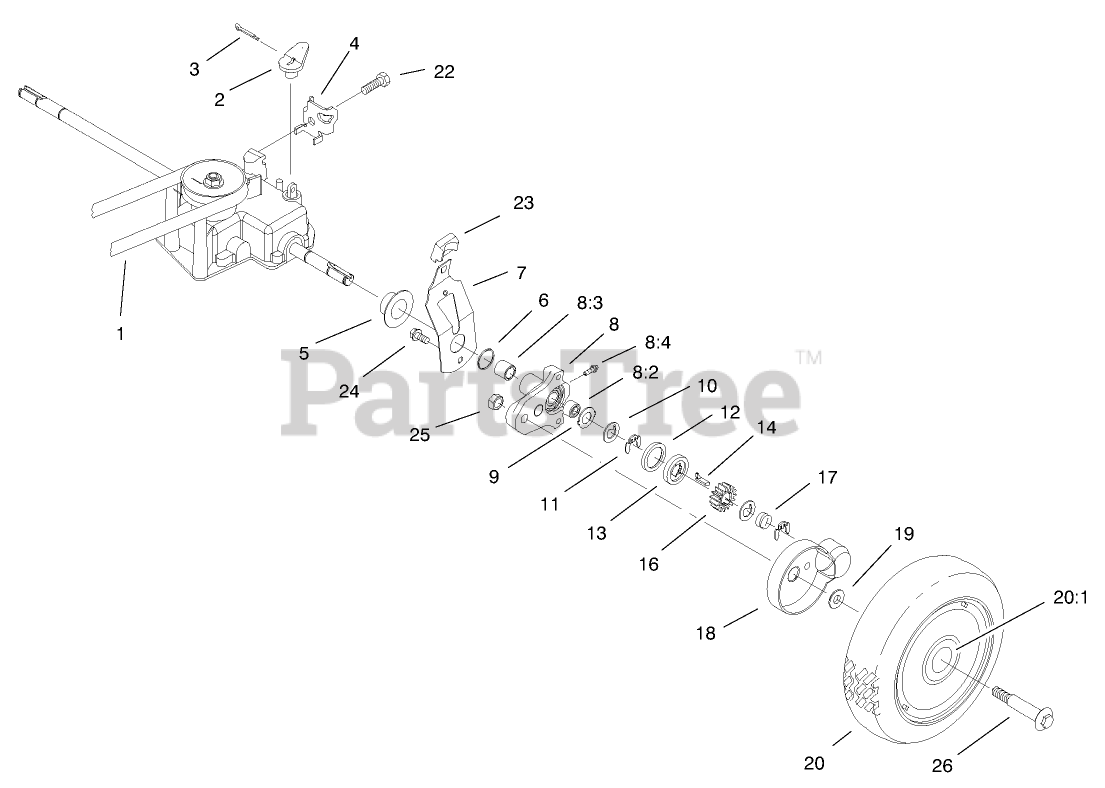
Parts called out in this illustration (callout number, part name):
1	V-BELT
2	LEVER-SHIFT
3	PIN-COTTER
4	CLAMP-CABLE
5	CAP-END
6	O-RING
7	SPRING ARM ASM
8	PIVOT ARM ASM
8:2	BUSHING
8:3	BUSHING
8:4	FITTING-GREASE
9	WASHER-ARM, PIVOT
10	WASHER-THRUST, KEYED
11	RING-RETAINING,CLIP
12	RING-FRICTION
13	WASHER-CLUTCH
14	KEY-ROCKING, LH
16	GEAR-PINION
17	SPRING-COMPRESSION
18	COVER-WHEEL
19	SPACER-COVER, WHEEL
20	WHEEL TIRE ASM (SP)
20:1	BUSHING
22	SCREW-HWHTF
23	KNOB-ARM
24	SCREW-HWH
25	LOCKNUT
26	BOLT-SHOULDER
